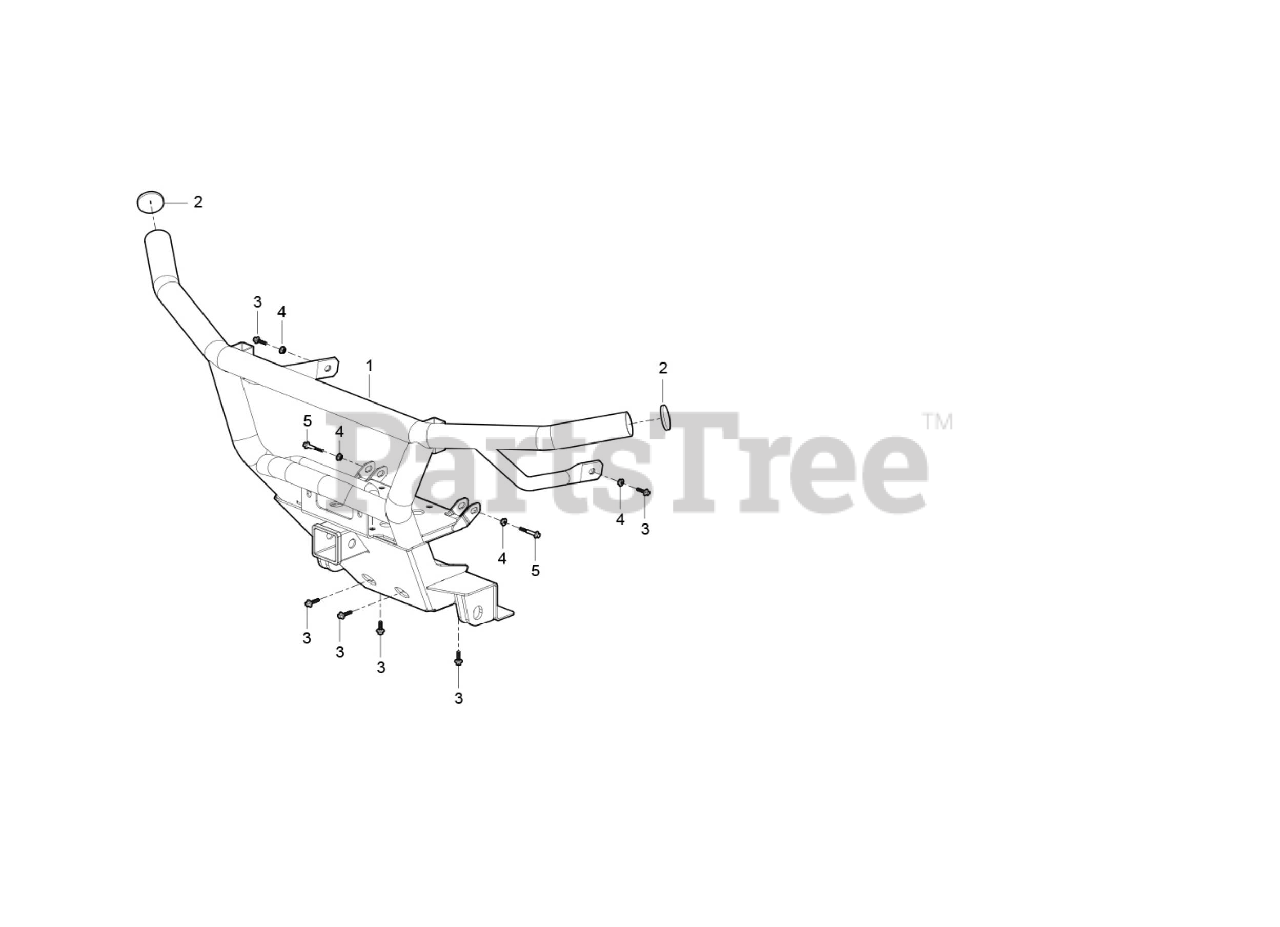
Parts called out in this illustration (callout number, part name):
1	FRONT BUMPER
2	COVER -CIRCULAR TUBE 38
3	Hexagon Flange Bolt M10x30
4	LOCK NUT M10x1.25
5	Hexagon Flange BoltM10x1.25x45
